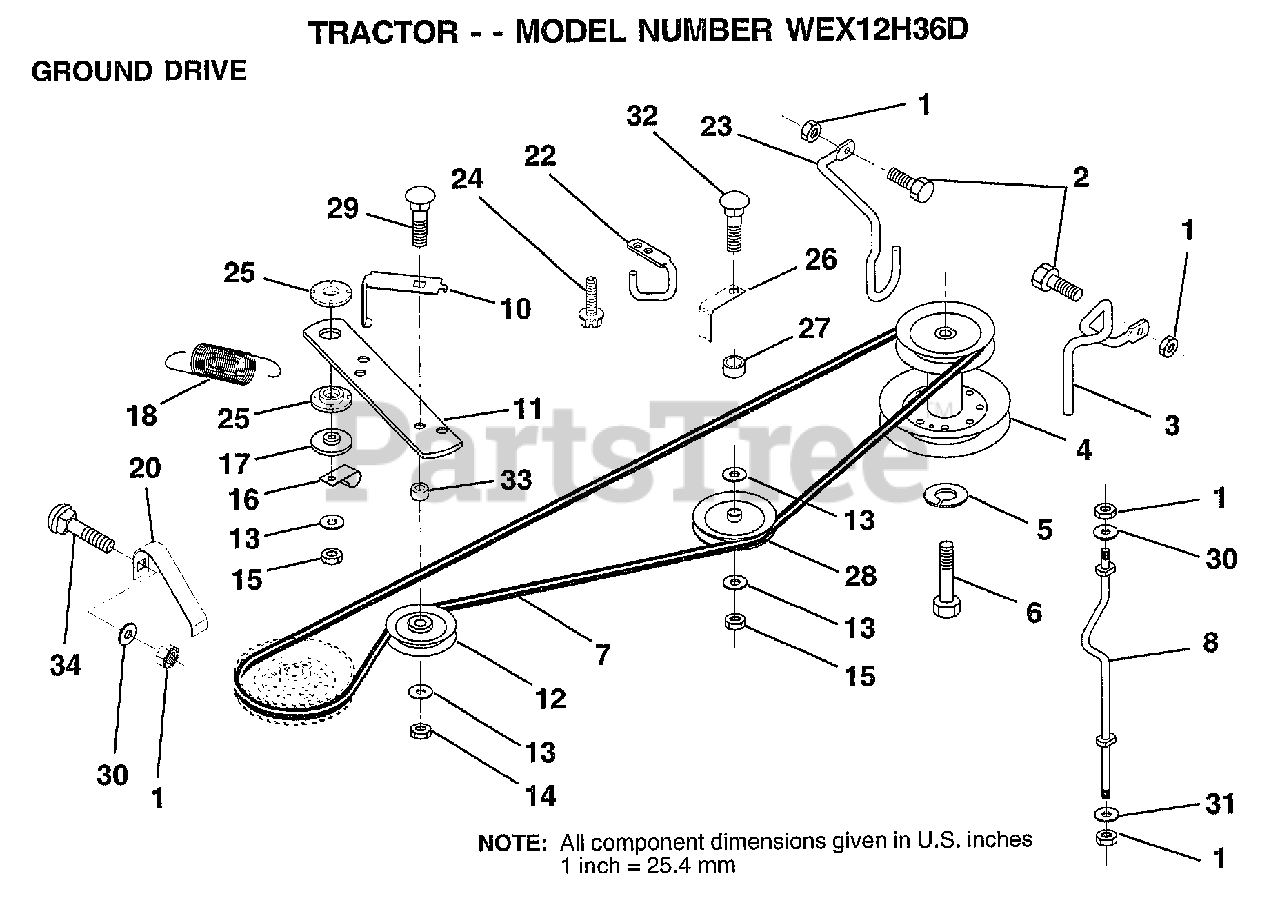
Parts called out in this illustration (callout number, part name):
1	NUT
2	BOLT
3	KEEPER.BELT.FRT.
4	PULLEY.ENGINE.LR
5	LOCKWASHER
6	HEX BOLT
7	BELT-V.DRV.77.75
8	KEEPER.BELT.HYDRO
10	KEEPER.BELT.GRD.
11	ARM-IDLER.DR.GRND
12	PULLEY.IDLER.FLAT
13	WASHER
14	LOCKNUT
16	"CLIP,INSULATOR"
17	SPACER
20	KEEPER.BELT.LH
22	"KEEPER,FRA DR BEL"
23	KEEPER MOWER LH
24	SCREW
25	BUSHING.NYLON
26	KEEPER.BELT.IDLER
27	SPACER.625X.843
28	PULLEY.IDLER.V.GR
29	BOLT RDHD 3/8-16
30	WASHER
31	WASHER M
32	BOLT
34	BOLT
